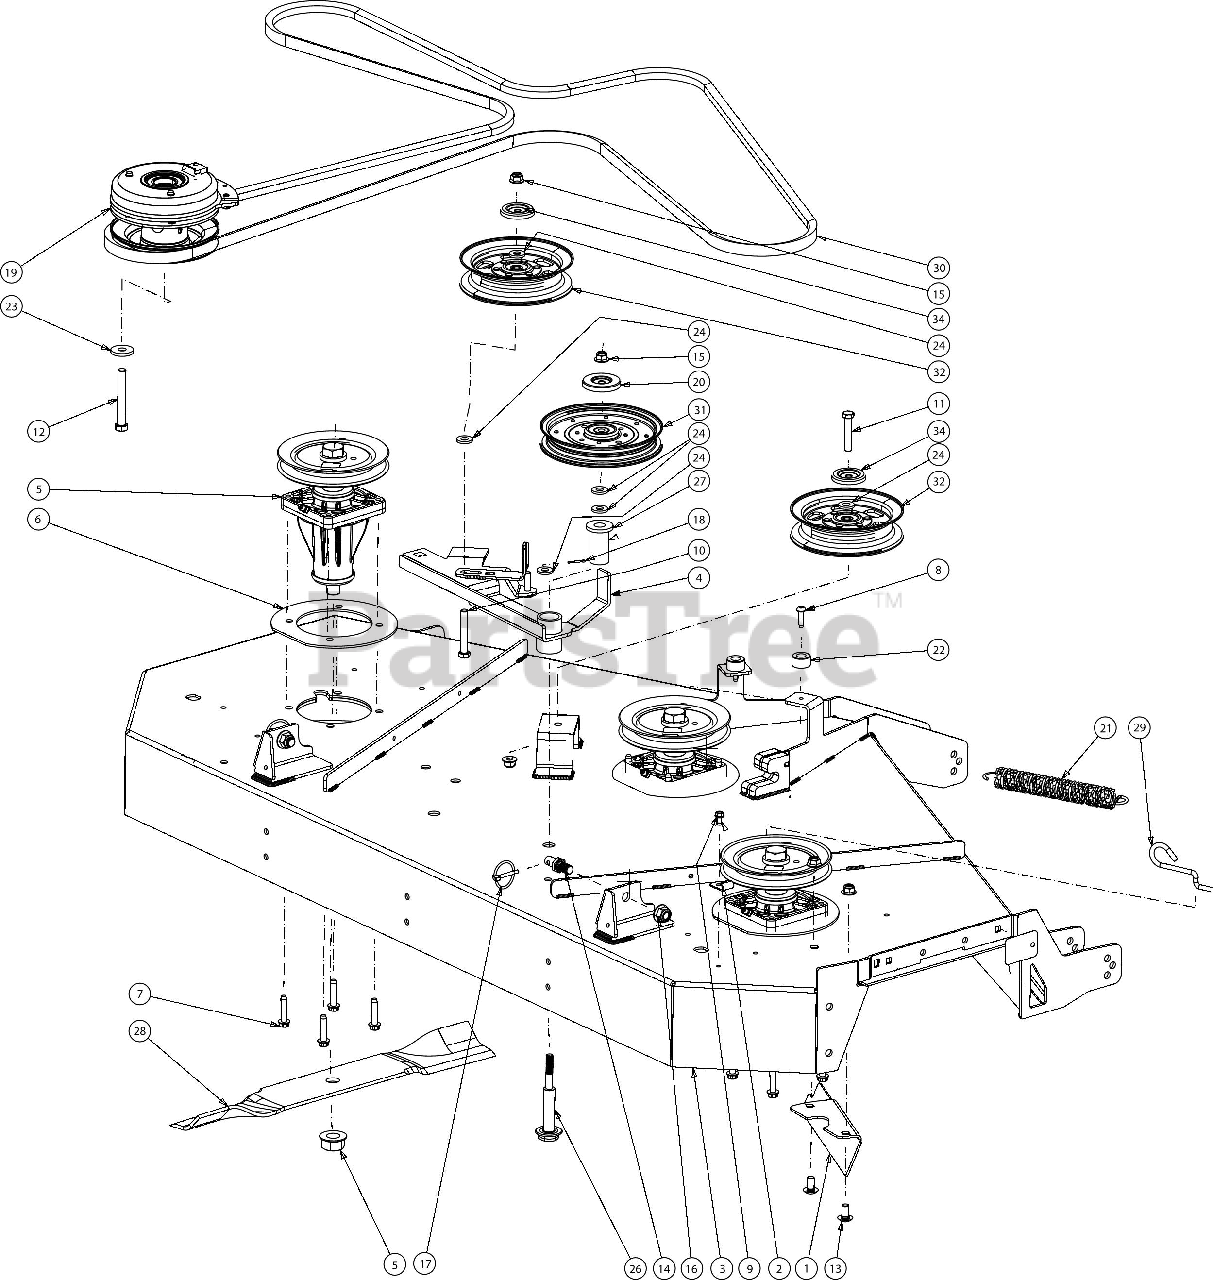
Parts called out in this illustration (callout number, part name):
1	CHUTE BAFFLE
2	HOOK RETAINER BRACKET
3	60" FAB DECK SHELL
4	54/60" DECK IDLER ASSEMBLY+A9:C34
5	SPINDLE ASSEMBLY
6	SPINDLE REINFORCEMENT PLATE
7	SCREW 5/16-18 X 1.50
8	SCREW 1/4-20 X 1.0
9	SCREW 1/4-20 X.500
10	HEX SCREW-3/8-16X2.5 GR5
11	SCREW 3/8-16 X 2.0 GR5
12	SCREW 7/16-20 x 3.25 GR5
13	CARRIAGE BOLT 3/8-16 X .75
14	DECK PIN
17	LYNCH PIN
18	COTTER PIN 3/32
19	ELECTRIC PTO CLUTCH
20	PULLEY CAP
21	EXTENSION SPRING
22	BUMPER
23	FLAT WASHER .445 X 1.248 X .170
24	FLAT WASHER
26	SHOULDER BOLT
27	SHOULDER SPACER
28	21 BLADE (HI LIFT)"
29	DECK SPRING HOOK
30	DECK BELT B X 161.75
31	IDLER PULLEY
34	IDLER PULLEY CAP
